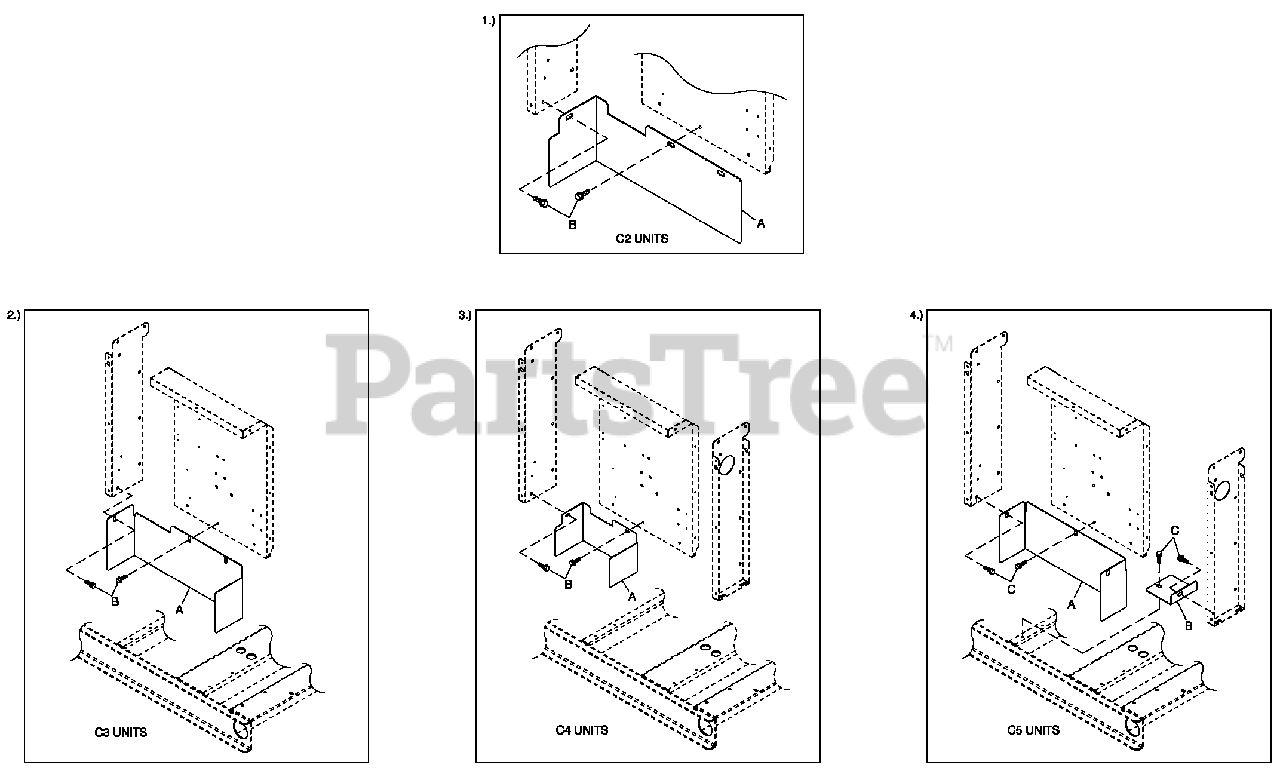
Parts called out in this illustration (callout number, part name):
1	C2 UNITS
2	C3 UNITS
3	C4 UNITS
4	C5 UNITS
A	SHIELD CONN BOX C2
B	SCREW THF M6-1 X 16 N WA Z/JS
A	SHIELD CONTROL STAND C3
A	SHIELD CONTROL STAND C4
A	SHIELD CONTROL STAND C5
B	SHIELD CONTROL STAND C5
C	SCREW THF M6-1 X 16 N WA Z/JS
